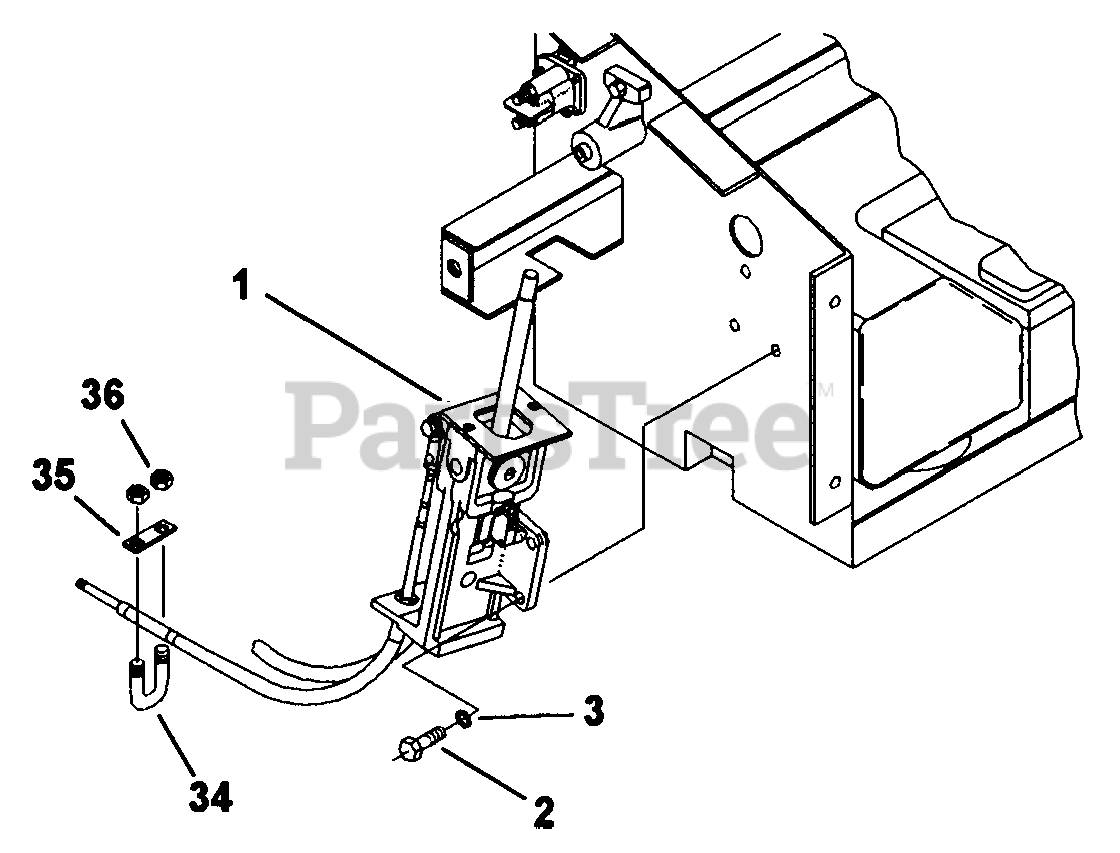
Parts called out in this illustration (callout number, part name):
1	JOYSTICK YOKE ASSEMBLY
2	CAP SCREW, 1/4-20 x 3/4", Gr.5
3	LOCK WASHER, 1/4" Split Ring
34	U-BOLT, 5/16-18 X 1 3/16"
35	U-BOLT SPACER
36	NUT, 5/16-18, Nylock
